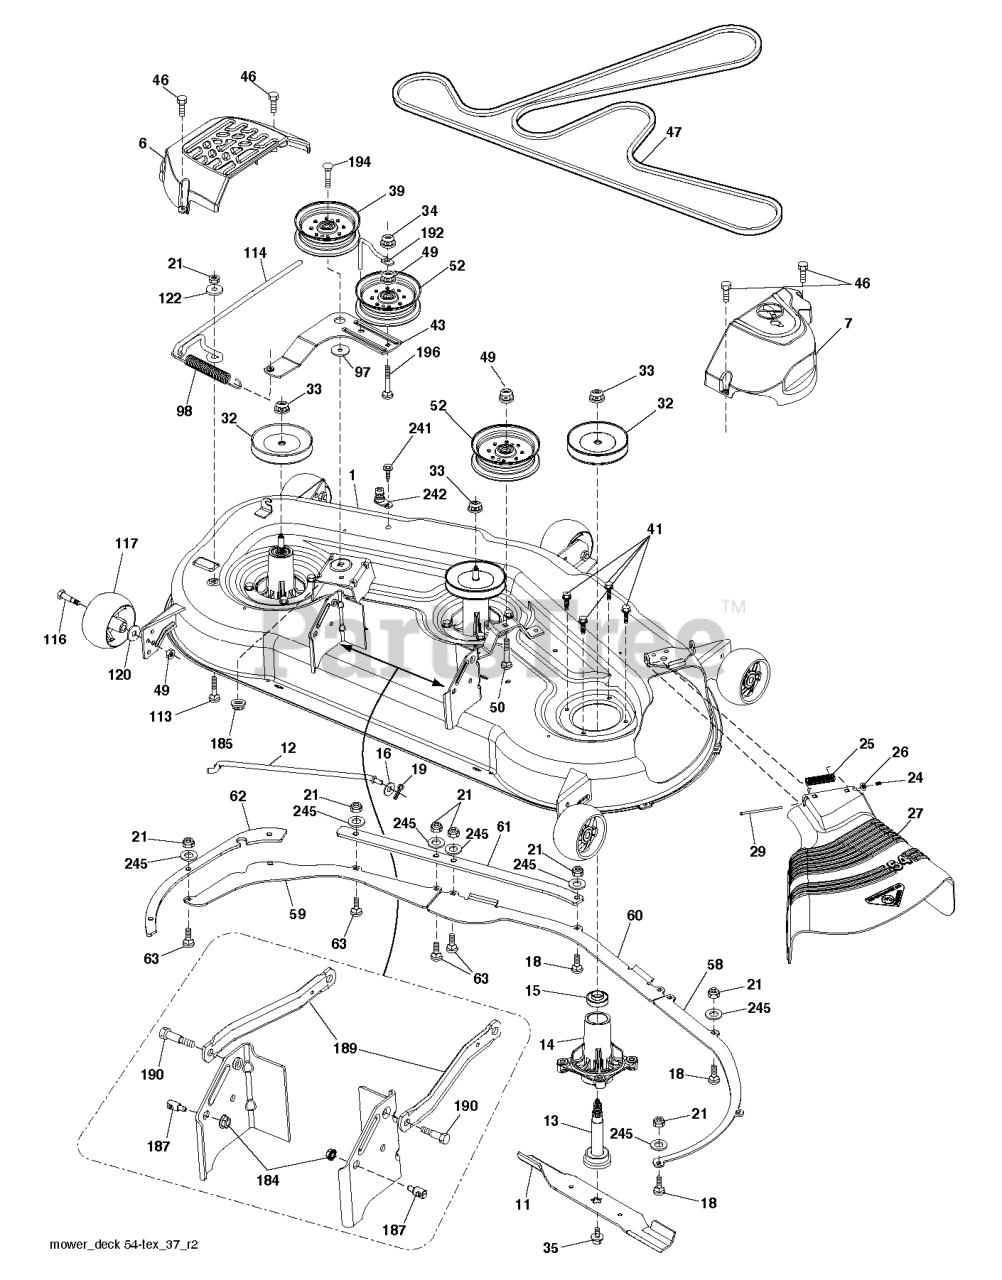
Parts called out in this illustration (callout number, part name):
1	DECK SVC 54"
6	COVER.MANDREL.LH.54"20
7	COVER.MANDREL.RH.54.20
8	BOLT.WASHER.ASM.7/16-2
11	BLADE.BAGGING.54"
11	54" MULCH BLADE
12	ROD.ANTI.SWAY.48/54"TE
13	SHAFT ASM MANDREL
14	RP.HOUSING.MANDREL.4PT.
16	WASHER
18	BOLT
19	PIN.COTTER.5/16.BOW TI
21	LOCKNUT
24	CAP-SLEEVE LT
25	SPRING, TORSION
26	NUT PUSH M
27	DEFLECTOR
29	ROD.HINGE
30	SCREW, WASHER HEAD
31	WASHER.SPACER.MANDREL
32	PULLEY/MANDREL
33	NUT.FLANGE.LOCK.TOP
39	RB PULLEY.IDLER.4.50/HUB SPEC
43	ARM.IDLER
46	SCREW.1/4-20X5/8
47	RP.BELT.DRIVE.54."2006
49	NUT LOCK FLG 3/8-16 UNC
50	BOLT
52	PULLEY.IDLER.2006
58	BAFFLE.RIGHT.54"
59	BAFFLE.LEFT.54"
60	BAFFLE CENTER 54" MOWER
61	PLATE.REIN.FRONT.BOLT54"X431
62	PLATE.REIN.SIDE.BOLT.54"X431
63	BOLT.CARRIAGE.5/16-18
98	SPRING, DECK DRIVE
113	BOLT CRT
114	ROD TENSION RELIEF
116	BOLT.SHOULDER.3/8-16X3-5/8.
117	RP WHEEL. GUAGE RALLY
120	WASHER
122	BUSHING.RELIEF.TENSION
184	NUT LOCK HEX FLANGE 5/16-18
185	NUT.LOCK.FLANGE.7/16
187	STUD.FASTNER.W/ANTI-ROTATE
189	ARM.SUSPENSION.MOWER
190	BOLT.SHOULDER
192	KEEPER.BELT.IDLER.54"T
194	BOLT.HEX.WASHER.HEAD.7/16-24X
196	BOLT
241	SCREW.TT.#10-32X.5.3/8.FLANGE
242	PORT.WASHOUT
